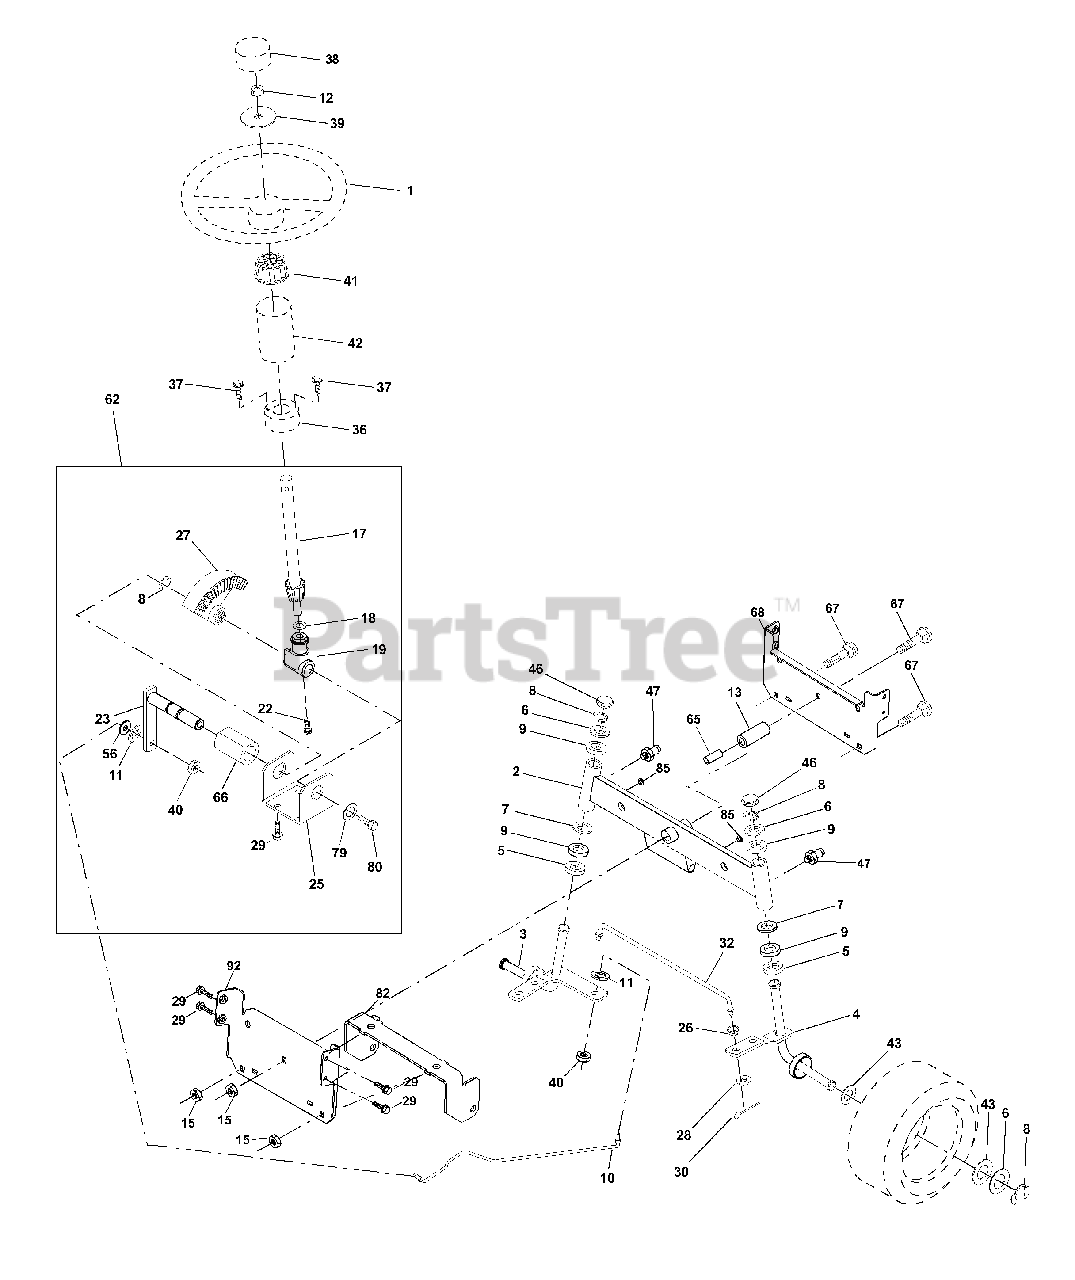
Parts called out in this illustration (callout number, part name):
1	Wheel Steering Auto Black
2	Axle Asm Front
3	Spindle Asm Lh
4	Spindle Asm Rh
5	Bearing Race Thrust Harden
6	Washer 25/32 X 1 5/8 X 16ga
7	Washer 27/32 X 1 1/4 X 16 Ga
8	Ring Klip #t5304-75
9	Bearing Col Strg Blk
10	Link Drag
11	Lockwasher
12	Nut Hex Jam Toplock 1/2-20 Unf
13	Spacer Bearing Axle Front
15	Nut Hex Flange Lock
17	Shaft Asm Strg
18	Washer Thrust 515x 750x 033
19	Support Shaft
22	Screw Hex Wsh Hd Torx
23	Shaft Asm Pittman
25	Bracket Steering
26	Bushing Rod Tie Blk Lt
27	Gear Sector
28	Washer 13/32 X 7/8 X 16ga
29	Screw 3/8-16x3/4
30	Pin
32	Rod Tie Wire Form 19 75 Mech
36	Bushing Strg
37	Screw TT #10-32 x 5 x 3/8 Flange
38	Insert Cap Strg
39	Washer .53 x 2.25 x .160 Zinc
40	Locknut Center
41	Adaptor Wheel Strg 640/ 635id
42	Boot Dash Steering
43	Washer 25/32 X 1 1/4 X 16 Ga
46	Cap Spindle Fr Top Blk
47	Fitting Grease
56	Washer 13/32 x 3/4 x 10 Ga.
62	Kit Steering Assembly Service
65	Spacer Axle
66	Bearing Arm Pittman
67	Bolt Rdhd Sq 3/8-16 Unc x 2-1/4
68	Brace Axle Front
79	Washer 13/32 x 1-1/4 x 12 Ga.
80	Bolt Hex Nylon 3/8-16 x 3/4
82	Bracket Susp Chassis Front
85	Fastner Christmas Tree
92	Axle Rear 16" Tires GTV
